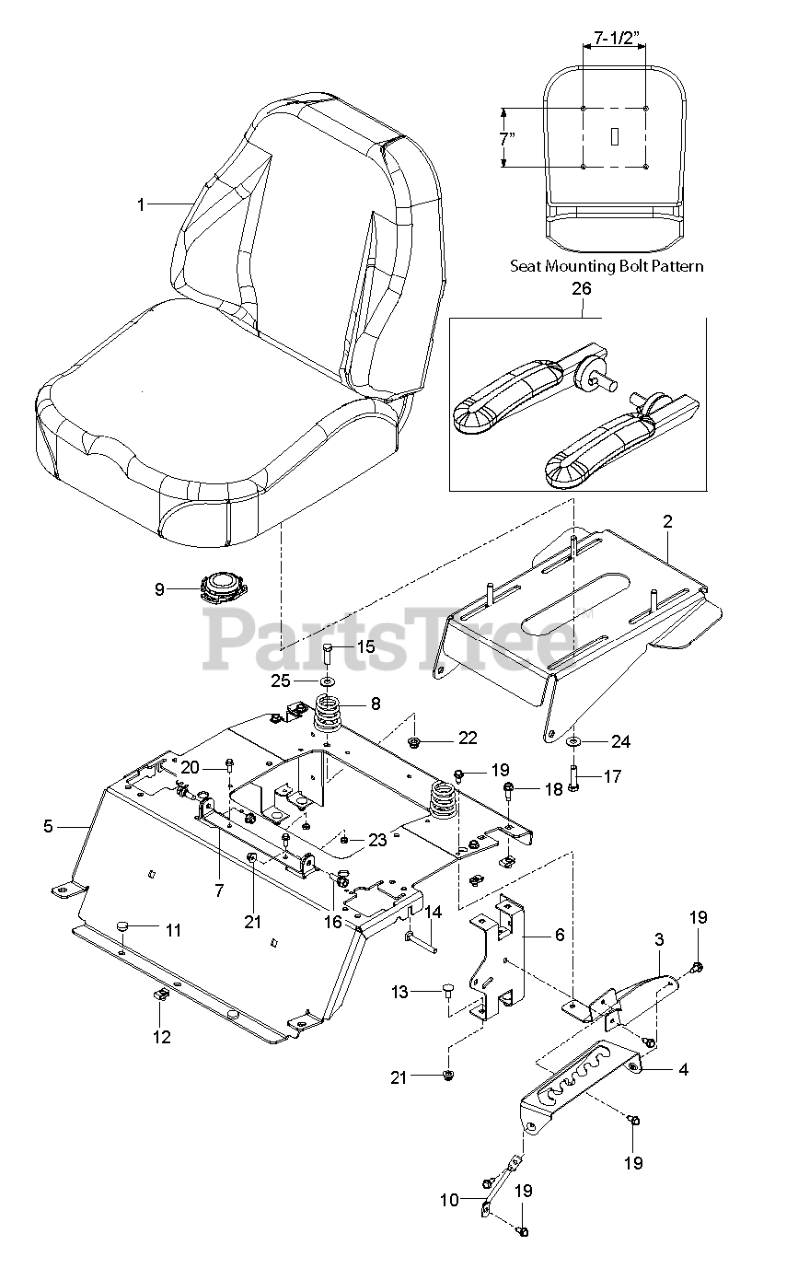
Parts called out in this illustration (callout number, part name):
1	SEAT. WOOD.BOTTOM.4-BOLT.HUSQ
2	PAN SEAT, 4-BOLT BLACK X428
3	PLATE.SUPPORT.DECK.LIFT.X431
4	PLATE.DECK.LIFT.X431
5	PLATE SEAT SUPPORT; RZ ORANGE
6	SUPPORT REAR SEAT BLACK
7	BRACKET.SEAT.REINF.X672
8	SPRING.COMPRESS.SEAT.TAPERED
9	SWITCH.SEAT.DELTA.OPC.
10	SUPPORT.LEG.DECK.LIFT
11	GROMMET.BUMPER
12	U-CLIP 5/16-18 NUT RETAINER
13	BOLT 5/16C X 3/4" CARRIAGE
14	RHSNB 5/16-18 X 2-1/2 GR5 ZD
15	BOLT
16	BOLT SHOULDER 5/16-18 UNC
17	BOLT.5/16-18X1-1/4 FULL.THREAD
18	SCREW.THDROL.5/16-18X3/4.TTY
19	BOLT.5/16HEX.WHS.HD
20	SCREW.FLG.LOCKING.1/4-20X.75
21	5/16-18 NYLOC FLANGE NUT
22	NUT 3/8-16 HEX FLG NYLOC ZD
23	NUT
24	WASHER
25	RP WASHER 3/8 FLAT
